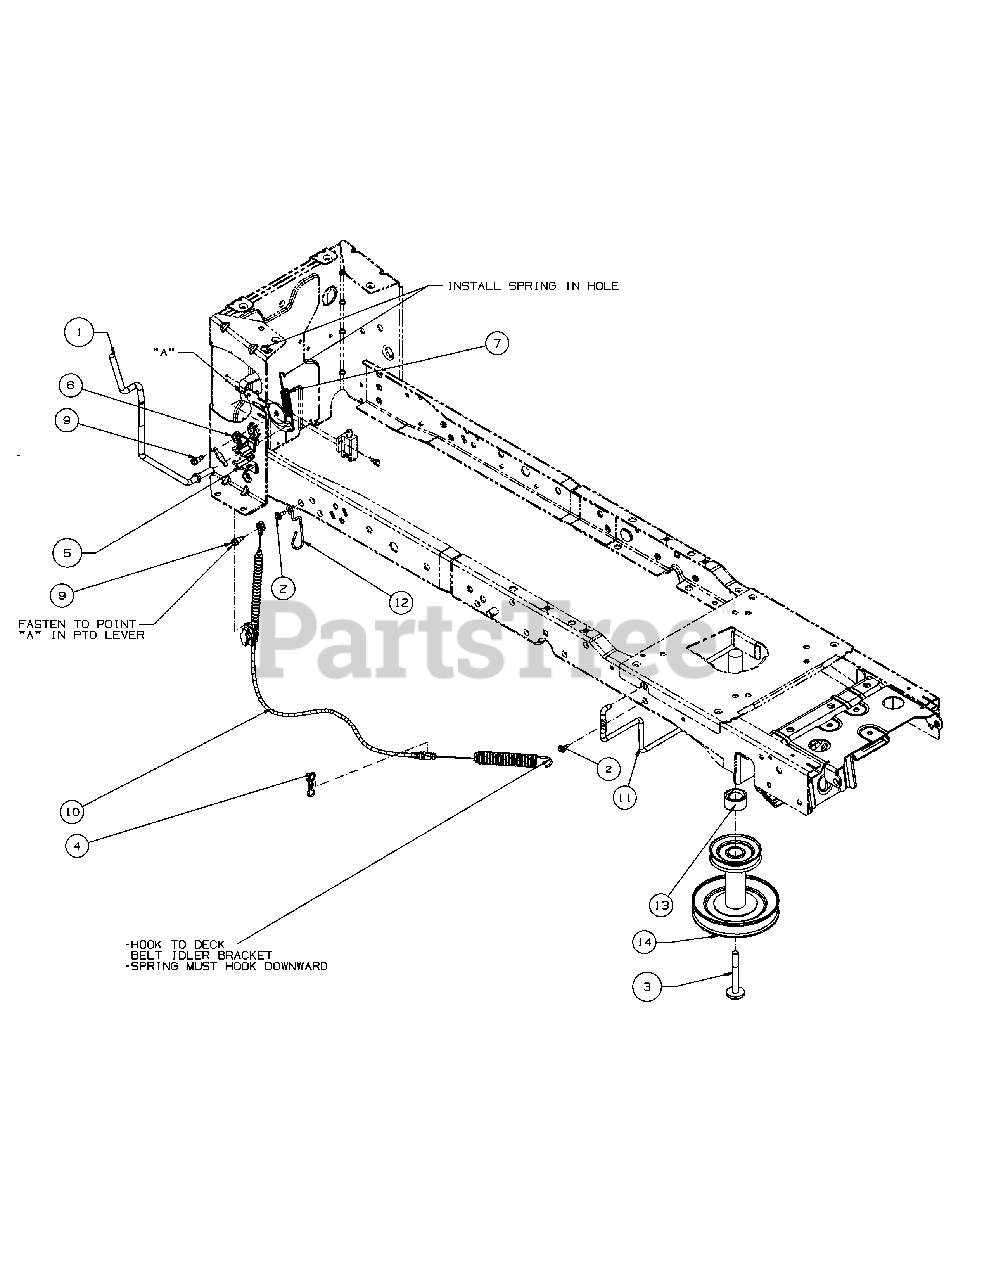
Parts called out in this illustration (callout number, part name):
1	Handle Asm-PTO
2	Screw-Hxacrnwsh M6-
3	Hhcs-Sems 7/16-20
4	Pin-Bow Tie Cotter
5	Pto Handle Mount
6	Pto Handle Mount, Top
7	Spring-Extn Pto
8	Grease:Anti-Sieze
9	Screw-Shoulder
10	Cable-PTO Handle
11	Rod-Belt Keeper Pltd
12	Wire-Cable Guide
13	Spacer-Eng Pulley
14	Pulley:Eng:3.56 X 6.12 Dia Hydro
